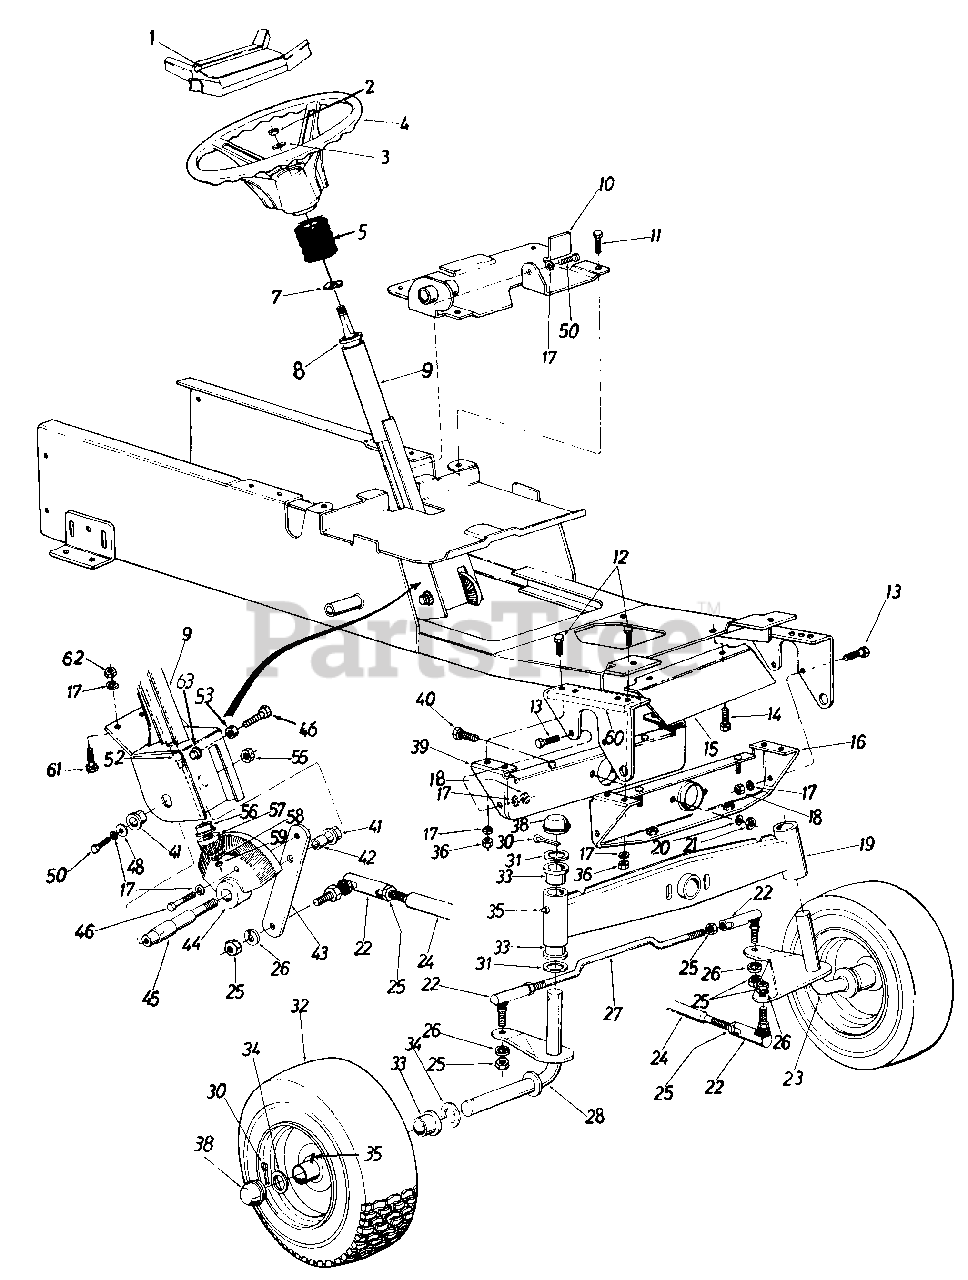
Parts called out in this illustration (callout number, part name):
1	Steering Wheel Insert
2	Hex Cent. L-Nut 5/16-24 Thd.
3	Bell-Wash. 5/16" I.D.
4	Steering Wheel
5	Steering Bellow
7	Wave Wash .660" I.D. x .88" O.D.
8	Ball Brg .63" I.D. x 1.38" O.D.
12	Hex Bolt 3/8-16 x 1.5" Lg.
13	Hex Bolt 3/8-16 x 1" Lg.
14	Hex Wash. S.F. Tap Scr. 3/8-16 x 1.25" Lg.
18	Hex Nut 3/8-16 Thd.
19	Pivot Bar Ass'y.
20	Bell-Wash. 3/8" I.D.
21	Hex Cent. L-Nut 3/8-16 Thd.
22	Drag Link End
23	Axle Ass'y.- L.H.
24	Drag Link
25	Hex Nut 1/2-20 Thd.
26	L-Wash. 1/2" I.D.
27	Tie Rod
28	Axle Ass'y.- R.H.
30	Cotter Pin 3/16" Dia. x 1.5" Lg.
31	Fl-Wash. 1.00" I.D. x 1.62"
33	Flange Brg. 1" I.D.
34	Fl-Wash. 1" I.D. x 1.25" Q.D.
35	Grease Fltting
36	Hex Nut 3/8-16 Thd.
38	Dust Cover
41	Flange Brg. w/Flats .753" I.D.
42	Steering Gear Shaft Spacer
43	Steering Arm
44	Bevel Gear
45	Steering Gear Shaft
46	Hex Bolt 3/8-16 x 1.5" Lg.
48	Fl-Wash .406" I.D. x 1.25" O.D.
50	Hex Bolt 3/8-16 x .75" Lg.
52	Steering Shaft
53	Hex Jam Nut 3/8-16 Thd.
55	Hex Ins. L-Nut 1/2-20 Thd.
56	Hex Flange Brg .630 I.D
57	Pinion Gear
58	Fl-Wash. 3/8" Dia
59	Hex Cent. L-Nut 5/16-24 Thd.
62	Hex Nut 3/8-24 Thd.
